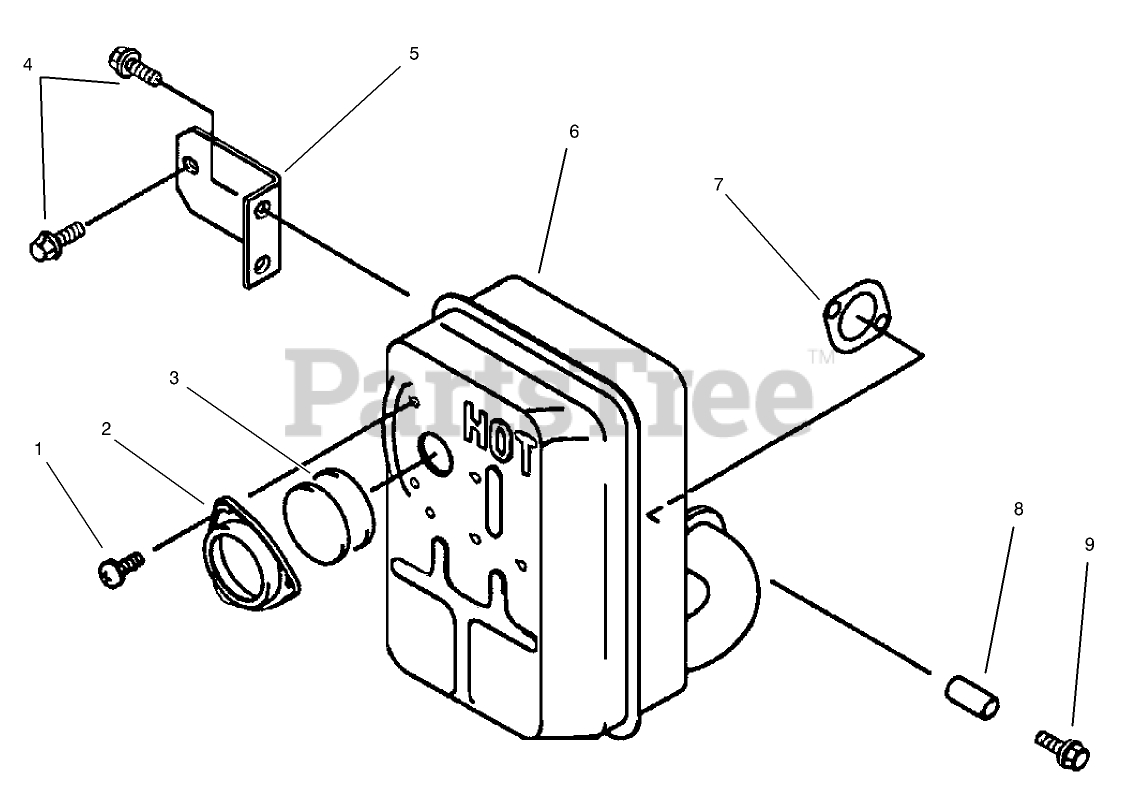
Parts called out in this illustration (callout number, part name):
1	Screw
2	Cap
3	Arrestor-Spark
4	Bolt-Flange
5	Bracket
6	Muffler ASM
7	Gasket-Muffler
8	Collar
9	Bolt-Flanged (8X45)
